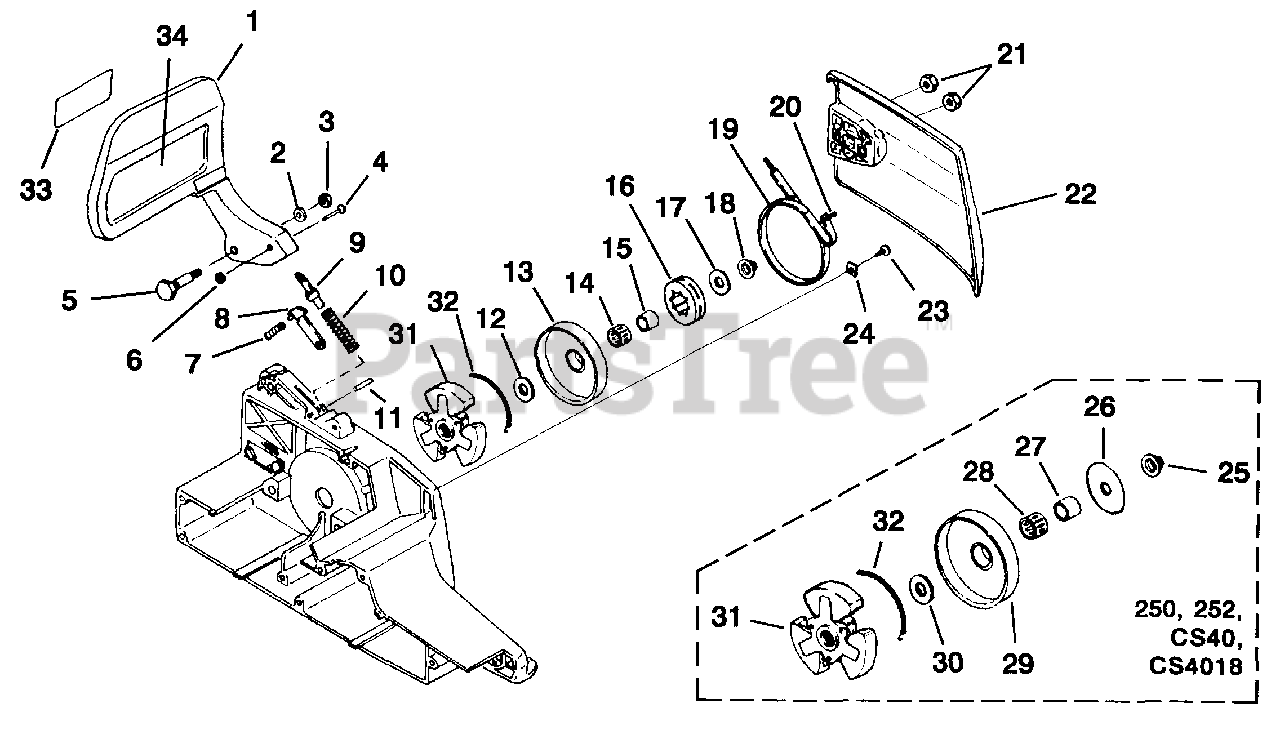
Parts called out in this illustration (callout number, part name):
1	GUARD, HAND
2	WASHER, BELLVILLE
4	PIN
5	SCREW, SHOULDER
6	RING, RETAINER
7	SPRING, COIL
8	BRAKE LATCH ASSY
9	ADJUSTER, BRAKE
10	SPRING, COMPRESSION
11	PIN
12	WASHER, THRUST (INNER)
13	SPLINE & DRUM
14	BEARING, NEEDLE
15	RACE, INNER
17	WASHER, THRUST
18	NUT, HEX LOCK (3/8"-24)
19	BRAKE BAND ASSY
20	PIN, DOWEL
21	NUT, HEX
22	COVER, DRIVE CASE
24	RETAINER, BRAKE BAND
25	NUT, HEX LOCK (3.8"-24)
26	WASHER, THRUST
27	RACE, INNER
28	BEARING, NEEDLE
29	SPROCKET & DRUM
30	WASHER, THRUST
31	CLUTCH ASSY
32	SPRING, CLUTCH
33	LABEL, KICKBACK
34	DECAL, SAFETY
